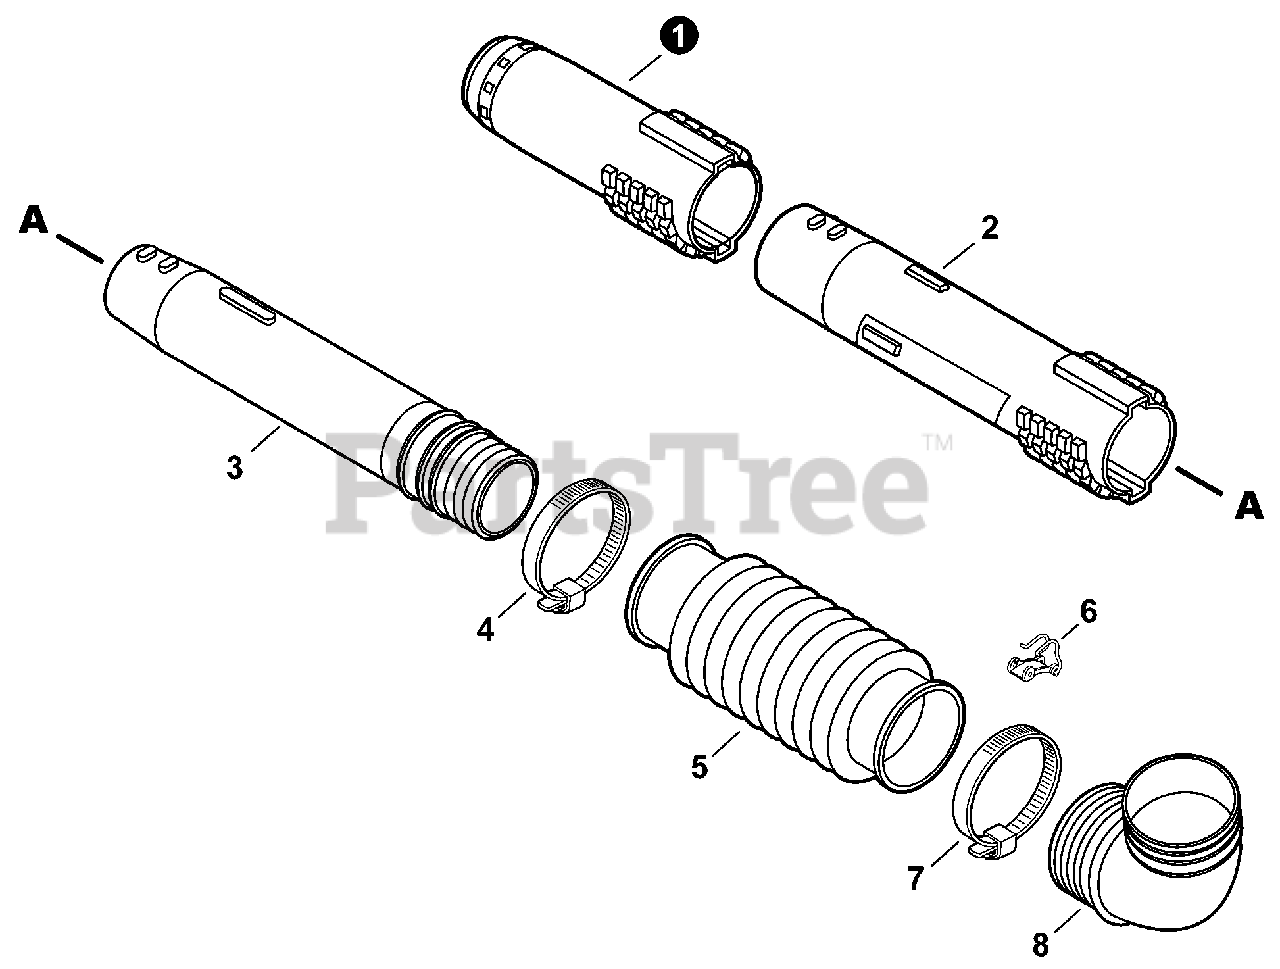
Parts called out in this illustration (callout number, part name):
1	TUBE, BLOWER - NOZZLE
2	TUBE, BLOWER - STRAIGHT
3	TUBE, BLOWER - SWIVEL
4	CLAMP 58.7MM / 82.5MM
5	TUBE, BLOWER - FLEXIBLE
6	CLIP, CABLE
7	CLAMP 77.8MM /101.6MM
8	TUBE, BLOWER - ELBOW
